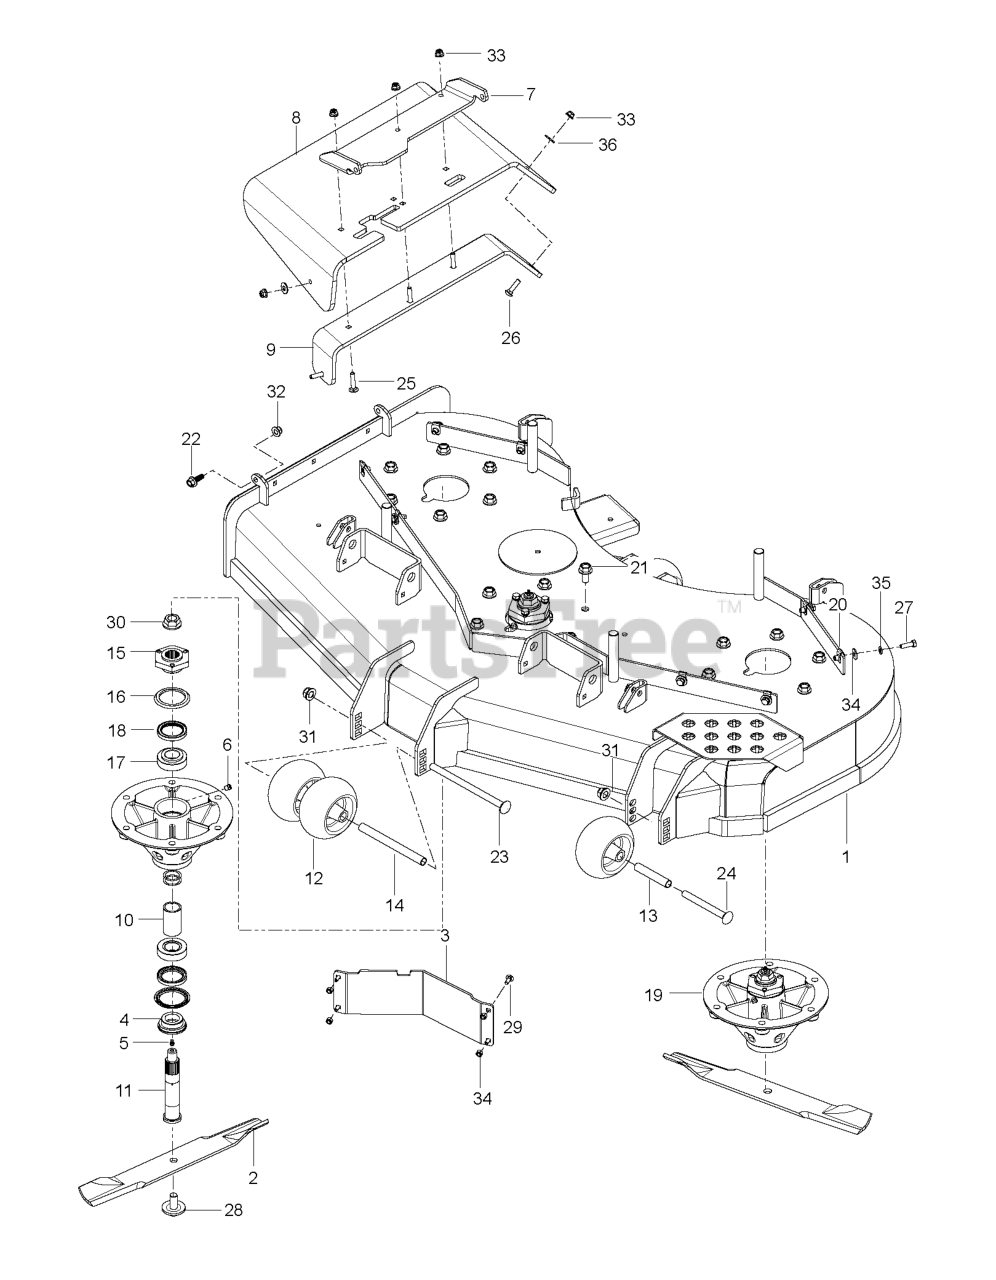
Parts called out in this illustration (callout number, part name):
1	DECK.SVC.W/DCL.CZT54X.MS672
2	BLADE, 19"
3	BAFFLE, DIVERTER 54"/60" LH
5	ZERK
6	PLUG-VENTED
7	BRKT - CHUTE MTG BLACK
8	CHUTE, DISCHARGE 48-52
9	BRKT, CHUTE SUPPORT BLACK
12	ROLLER, GAUGE .635 BORN
13	TUBE, ROLLER AXLE
14	TUBE, ROLLER AXLE LONG
16	SEAL V-RING 55MM
17	BEARING
18	SEAL SHAFT
19	SPINDLE.ASM.10".IRON.1/8-27
20	U-CLIP 5/16-18 NUT RETAINER
21	HHFS 1/2-13 X 1 GR5 ZD
22	HHFS 3/8-16 X 1 GRD 5 ZD
23	RHSNB 1/2-13 X 8 GR5 ZD
24	RHSNB 1/2-13 X 4.75 GR5 ZD
25	RHSNB 5/16-18 X 1-1/2 GR 5 ZD
26	BOLT, CARRIAGE 5/16X1-1/4
27	HCS 5/16C X 1
28	BLADE BOLT/WASHER
29	1/4-20X3/4 CARR BLT
30	NUT FLANGE 3/4-16
31	NUT, 1/2-13 HEX FLG NYLOC ZD
32	NUT 3/8-16 HEX FLG NYLOC ZD
33	5/16-18 NYLOC FLANGE NUT
34	RP_NUT 1/4-20 NYLOC
35	WASH.5/16.SLW.ZD
36	WASHER
